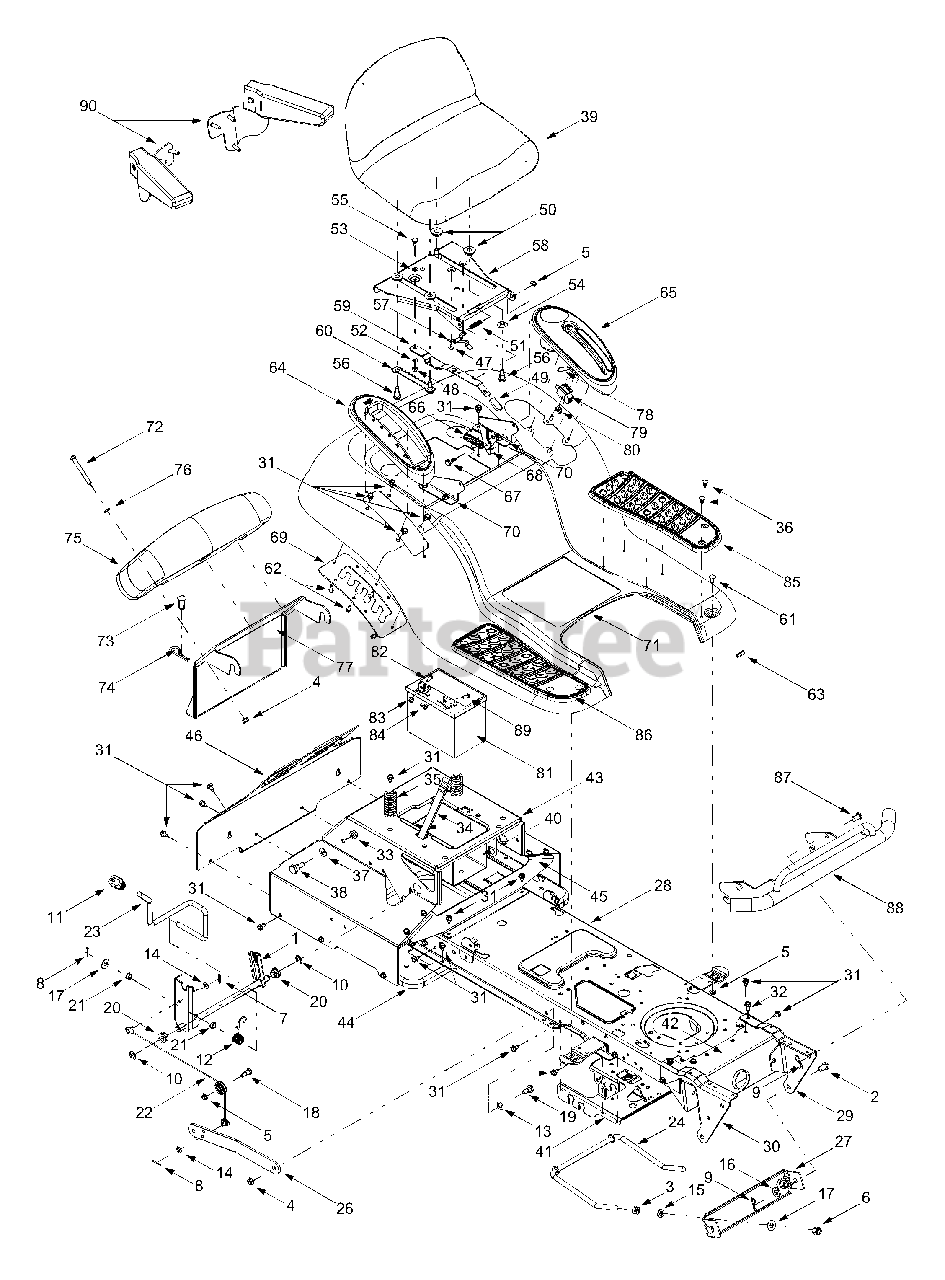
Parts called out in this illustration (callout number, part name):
1	Lift Shaft Assembly
2	Clevis Pin, .5 x .78
3	Hex Nut, 1/2-13
4	Flange Lock Nut, 3/8-16
5	HEX FLANGE NUT
6	Hex Nut, 1/2-13
7	Internal Cotter Pin
8	Cotter Pin, 3/32 x 1.0
9	Internal Cotter Pin
10	E-ring
11	Handle Grip
12	Torsion Spring
13	Flat Washer, .53 x .93 x .050
14	Flat Washer, .344 x .688 x .065
15	Lock Washer, 1/2
16	Flat Washer, .31 x 1.062 x .134
17	Flat Washer, .51 x 1.12 x .06
18	Hex Cap Screw, 5/16-18 x .62
19	SHOULDER SCREW .498 DIA x .340
20	Hex Flange Bearing
21	Snap Flange Bearing
22	Lift Cable, 16.16
23	Lift Handle
24	Deck Stabilizer Rod
25	Roller Pulley
32	Self-tapping Screw, 5/16-18 x .75
33	Flange Lock Nut, 7/16-20
34	Battery Strap
35	Compression Spring, 1.28 x 3.5
36	Ratchet Clip, .25
37	Bell Washer, .45 x 1.0 x .062
38	Shoulder Screw, .625 x .50, 7/16-20
39	Seat, High Back (Black)
48	Hex Flange Lock Nut, 1/4-20
49	Seat Adjuster Grip
50	Spacer
51	Compression Spring, .41 x 1.5
52	Spring Washer, .265 x .562 x .025
53	Flat Washer, .344 x .62 x .03
54	Flat Washer, .31 x 1.062 x .134
55	Shoulder Screw, .340 x .285,1/4-20
56	Shoulder Screw, .50 x .50, 3/8-16
57	Seat Stop
60	Seat Adjustment Selector
61	Carriage Screw, 5/16-18 x .62
62	Self-tapping Screw, 1/4-15 x .75
63	Trim Strip
64	Lift Lever Cover
65	Parking Brake Lever Cover w/ Cup Holder
66	Extension Spring, .750 x 3.8
67	Shoulder Screw, .437 x .286
68	Seat Lift Bracket
69	Lift Adjuster Bracker
73	Clevis Pin, .62 Diameter
74	Internal Cotter Pin, .148 x 3.0
75	Rear Bumper Weight
76	Flat Washer, .407 x .812 x .135
79	Plunger Switch (Parking Brake)
80	Pan Phillips Screw, #12-16 x .625
81	Battery, 270 CCA
82	Hex Cap Screw, 1/4-20 x .75
83	Hex Sems Nut, 1/4-20
84	WING NUT 1/4-20
85	LH Foot Pad
86	RH Foot Pad
87	Clevis Pin, .50 x .78
88	Bumper Assembly
89	Shoulder Screw, 1/4-20, .25 x .15
90	Arm Rest Assembly
